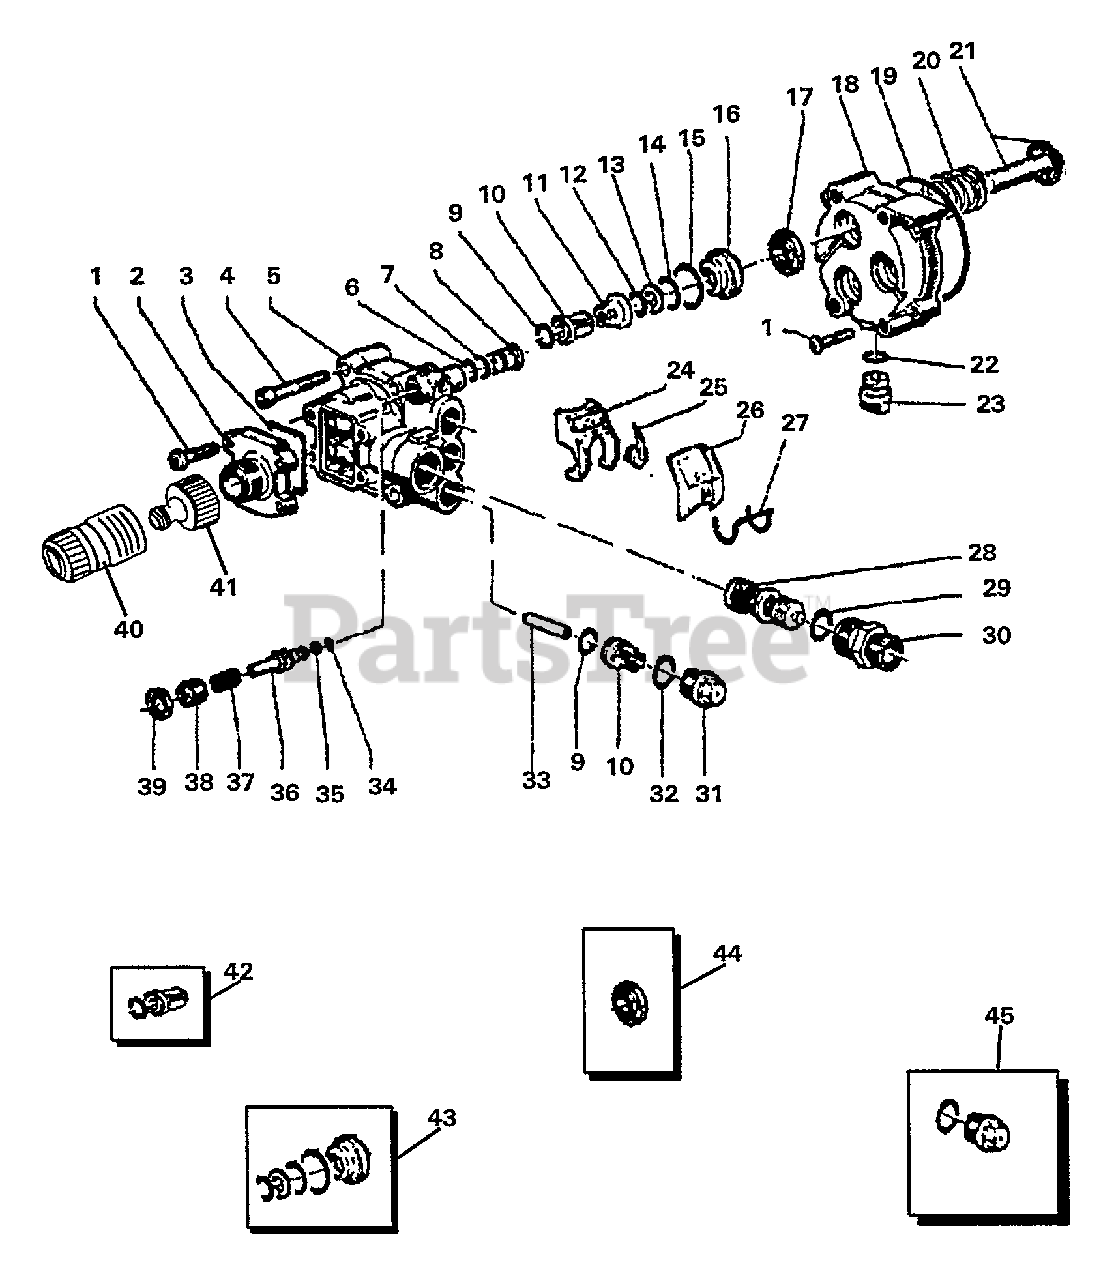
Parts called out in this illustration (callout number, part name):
1	SCREW - 6×30
3	O-RING 1.549×.103
4	SCREW - 8×50
5	HEAD, PUMP
6	O-RING 0.344×.070
7	O-RING 0.299×.103
8	CYLINDER, PRESSURE GAUGE
9	O-RING
10	UNIT VALVE
11	SPACER
12	O-RING 0.469×.103
13	RING
14	O-RING 0.739×.070
15	O-RING 0.937×.103
16	SPACER
17	SEAL, OIL
18	FLANGE
19	O-RING 3.237×.103
20	SPRING
21	PISTON
22	O-RING
23	PLUG
24	DIAL
25	INDICATOR
26	COVER, DIAL
27	SPRING, TORSION
28	VALVE KIT
29	O-RING 0.797×.103
30	FITTING, OUTLET
31	PLUG, M18
32	O-RING, 0.614×0.070
33	PIN
34	O-RING 0.118×.079
35	RING, BACK-UP, 0.114×0.070
36	GAUGE, PISTON
37	SPRING
38	SCREW M14×1
39	NUT M14×1×17×3
40	COUPLING, QUICK CONNECT - FEMALE
41	COUPLING, QUICK CONNECT - MALE
42	VALVE KIT
43	VALVE PACKING KIT
44	KIT, OILSEAL (3)
45	KIT, PLUG (3)
